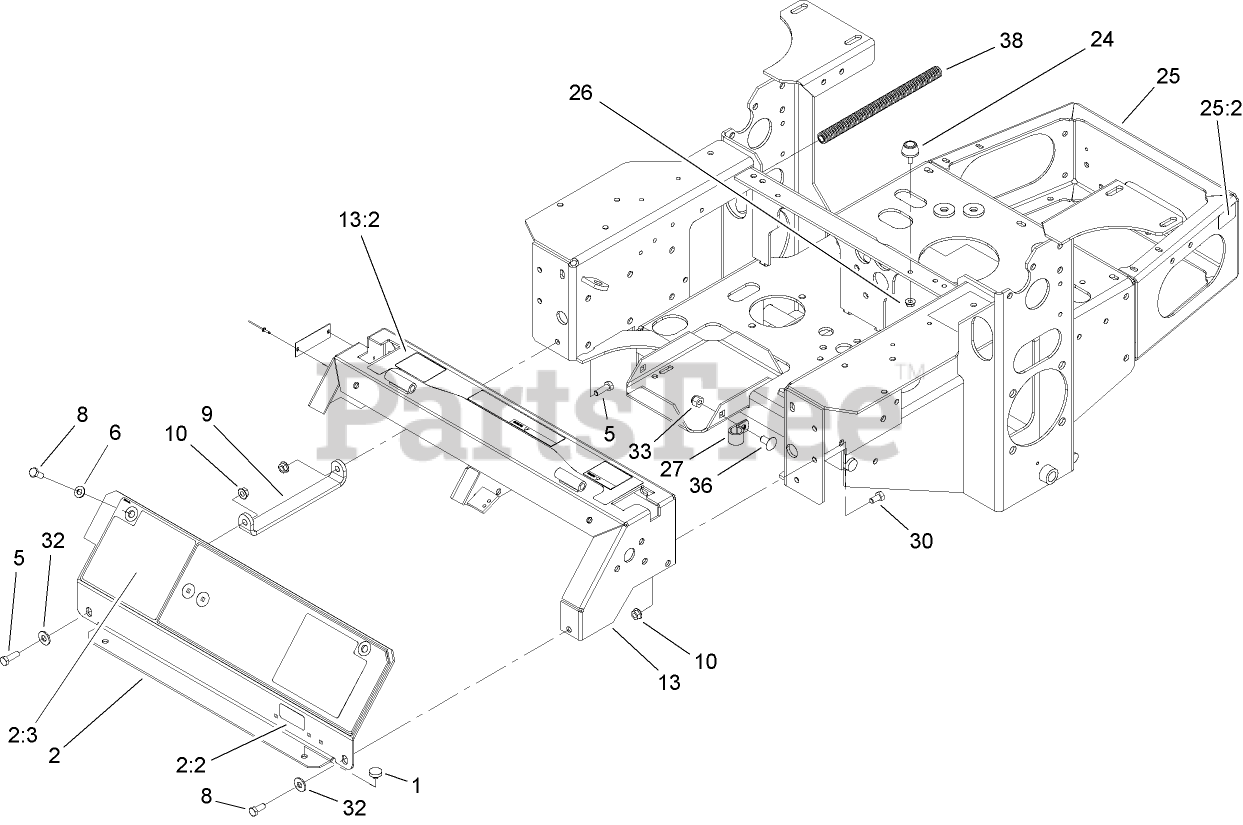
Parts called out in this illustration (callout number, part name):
1	BUMPER
2	PANEL ASM
2:2	DECAL-PROTECTION, EAR
2:3	DECAL-COVER, PANEL
5	SCREW-HH
6	WASHER-PLAIN
8	SCREW-HH
9	BRACKET
10	NUT-HF
13	CONSOLE ASM
13:2	DECAL-WARNING
24	BUMPER
25	MAIN FRAME ASM
25:2	DECAL-SURFACE, HOT
26	NUT-HF
27	CLIP-LOOM
30	SCREW-HH
32	WASHER-FLAT
33	NUT-LOCK, NI
36	SCREW-CARR
38	CONDUIT-CONVOLUTED, SPLIT
